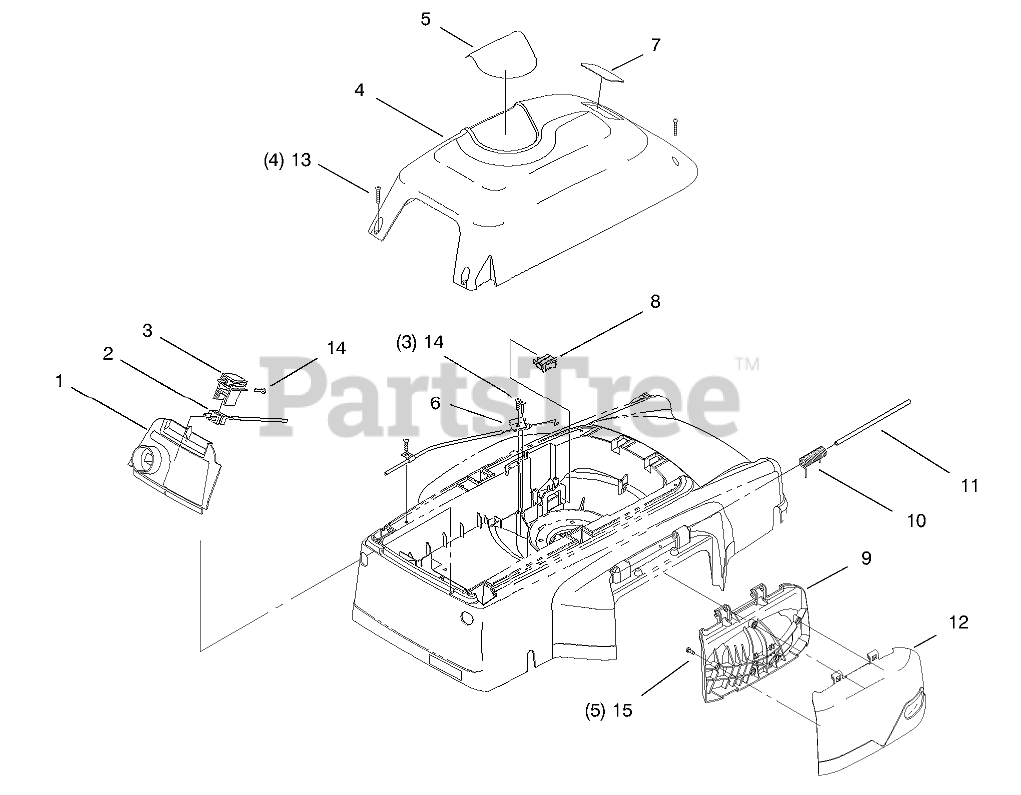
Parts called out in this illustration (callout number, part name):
1	PANEL ASM
3	HOUSING - PLUG
4	COVER ASM
5	DECAL
6	BRACKET - CABLE
7	PLATE-LOGO
8	SWITCH
9	OBS MULCH PLUG - INSIDE
10	SPRING - TORSION
11	PIN - HINGE, MULCH PLUG
12	MULCH PLUG - OUTSIDE
13	SCREW-PPH
14	SCREW-PPH
15	SCREW
